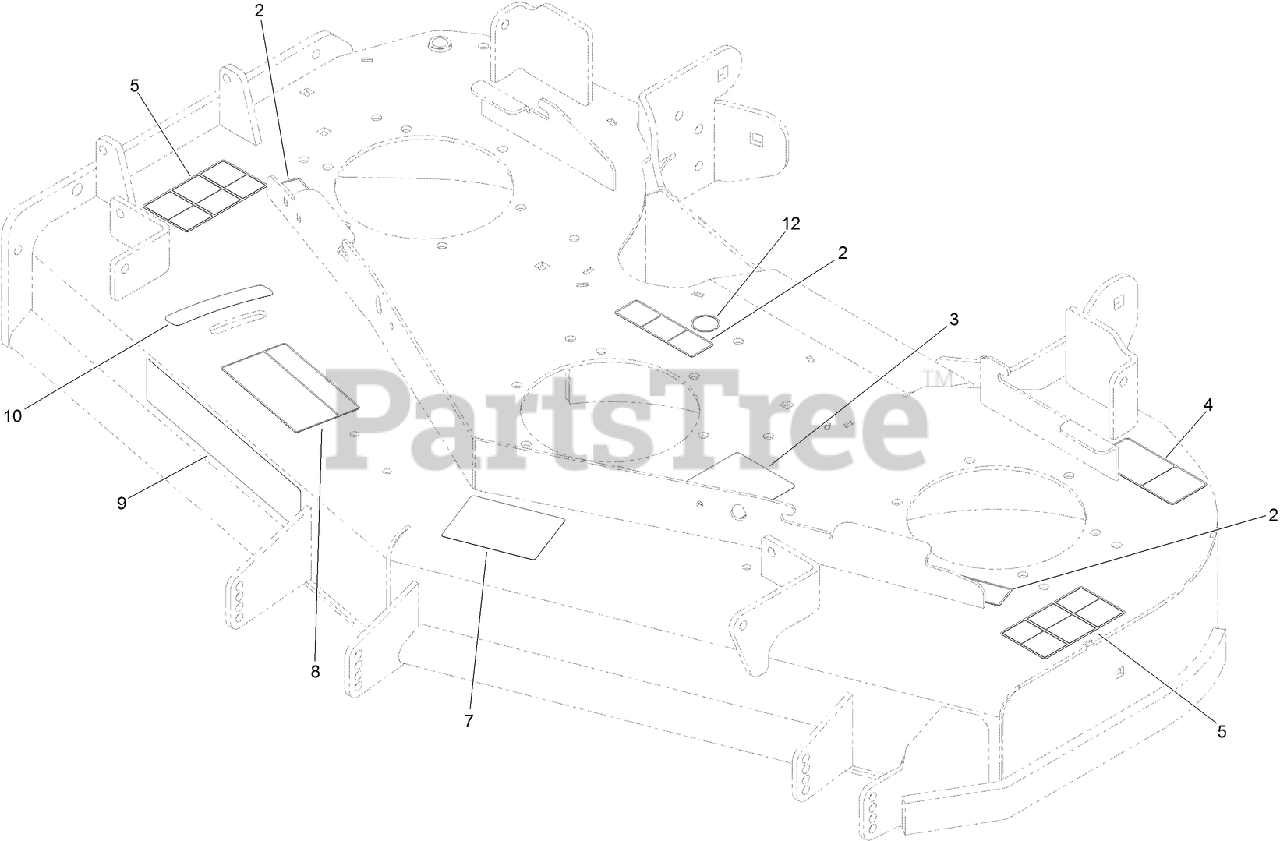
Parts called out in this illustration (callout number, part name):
2	DECAL-MISSING, COVER
3	DECAL-ROUTING, DECK BELT
4	DECAL-TORQUE, BLADE BOLT
5	DECAL-DANGER
7	DECAL-SCALP, ANTI
8	DECAL-ADJUSTMENT, BAFFLE
10	DECAL-SETTING, BAFFLE
12	DECAL-GREASE
